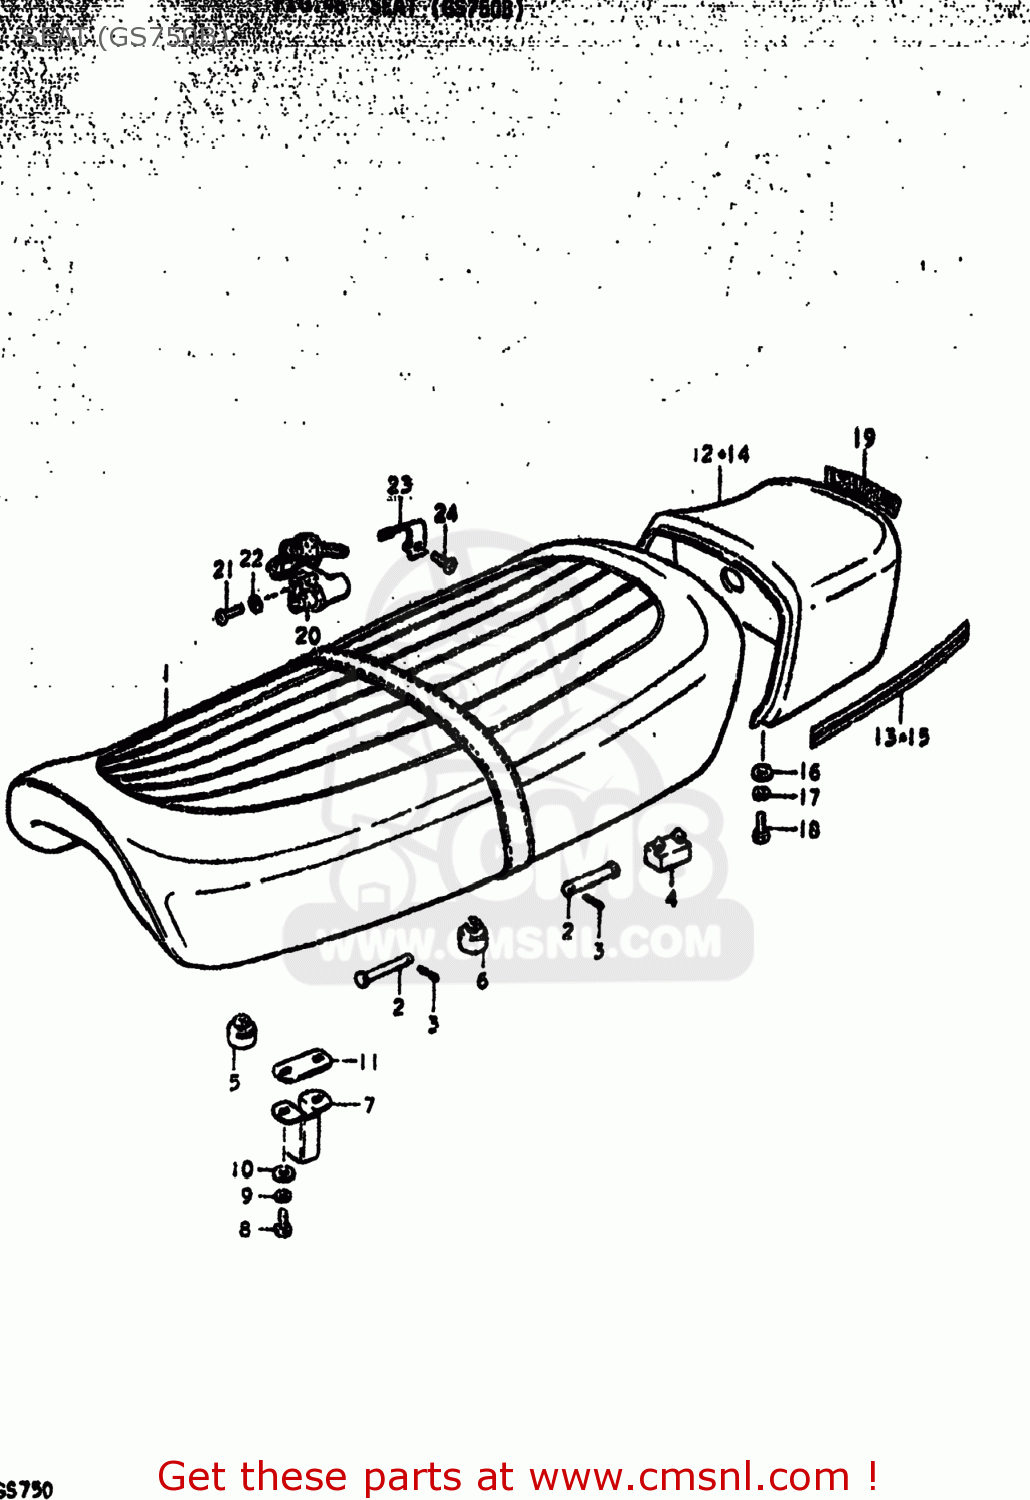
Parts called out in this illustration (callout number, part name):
1	SEAT ASSEMBLY
2	PIN
3	PIN
4	CUSHION
5	CUSHION(11.5X22X20)
6	CUSHION
7	STRIKER,SEAT LOCK
8	SCREW 6X12
9	LOCK WASHER
10	WASHER
11	SHIM,SEAT LOCK STRIKER
12	COVER,SEAT TAIL
13	TAPE SET,SEAT TAIL COVER
14	COVER,SEAT TAIL
15	TAPE SET,SEAT TAIL COVER
16	WASHER
17	LOCK WASHER
18	BOLT, UPPER
19	EMBLEM
20	LOCK ASSEMBLY,SEAT
21	Screw
22	LOCK WASHER
23	SPRING,HELMET HOLDER
24	SCREW
